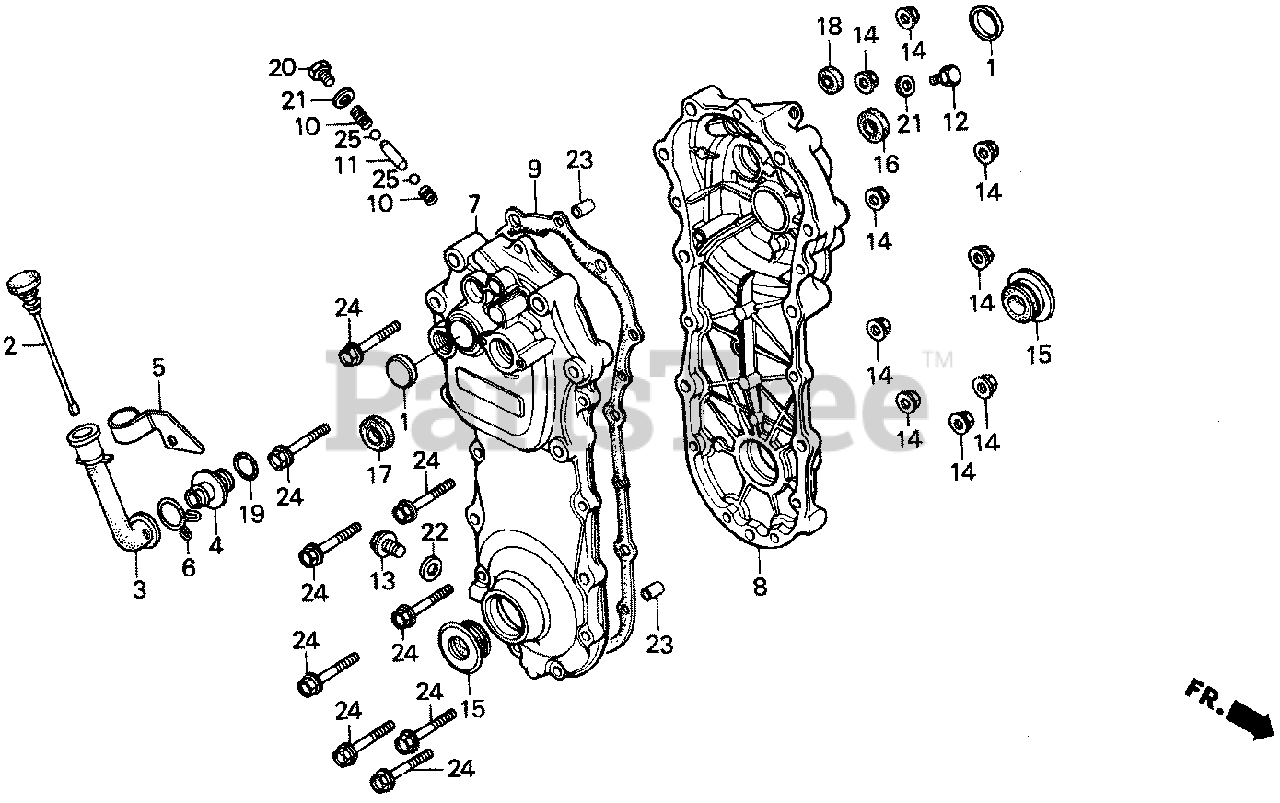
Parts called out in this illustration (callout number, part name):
1	PLUG, SEALING (30MM)
2	DIPSTICK, OIL
3	PIPE, OIL FILLER
4	JOINT, OIL PIPE
5	STAY, OIL PIPE
6	CLIP, AIR HOSE (20.5MM)
7	CASE, R. TRANSMISSION
8	CASE, L. TRANSMISSION
9	GASKET, TRANSMISSION CASE
10	SPRING, BALL SETTING
11	PIECE, INTERLOCK
12	BOLT, HEX. (8X10)
13	BOLT, DRAIN PLUG
14	NUT, FLANGE (6MM)
15	SEAL, WATER
16	OIL SEAL (17X30X8)
17	OIL SEAL (15X30X7)
18	OIL SEAL (12X22X6)
19	O-RING (16MM)
20	BOLT, HEX. (8X10)
21	WASHER, PLAIN (8MM)
22	WASHER, DRAIN PLUG (12MM)
23	PIN A, DOWEL (8X14)
24	BOLT, FLANGE (6X35)
25	BALL, STEEL (#8) (1/4)
